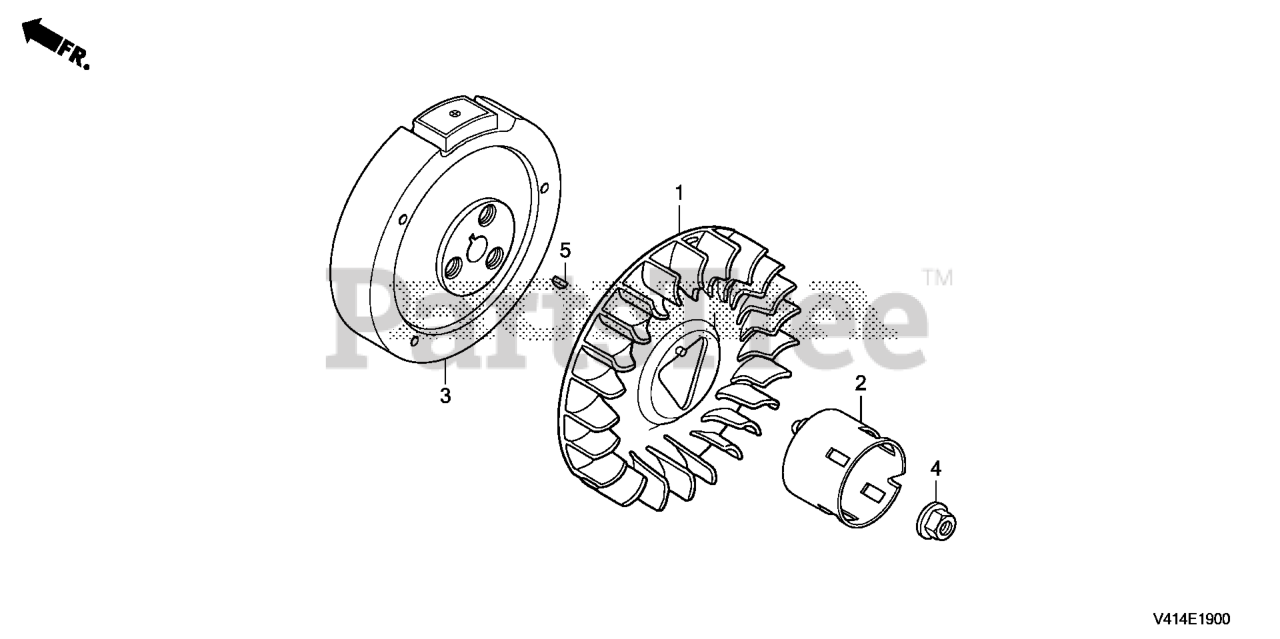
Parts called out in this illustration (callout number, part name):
1	FAN, COOLING
2	PULLEY, STARTER
4	NUT, SPECIAL (16MM) (1)
5	KEY, SPECIAL WOODRUFF (25X18)
